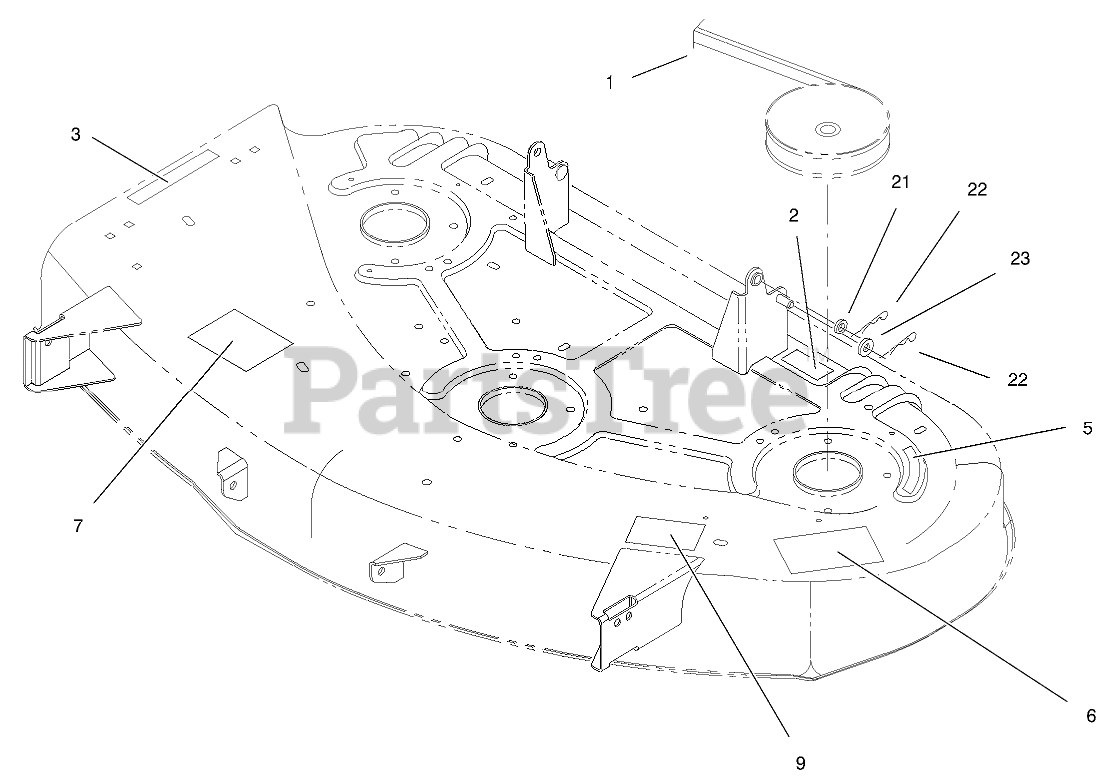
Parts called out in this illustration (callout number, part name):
1	V-BELT, 44IN DECK
2	DECAL-WARNING
3	DECAL-DANGER
5	DECAL-DANGER, SHIELD
6	DECAL-DANGER
7	DECAL-INSTALL, BELT
9	DECAL-ADJUSTMENT, WHEEL
21	WASHER-FLAT
22	PIN-COTTER
23	WASHER-HARDENED
